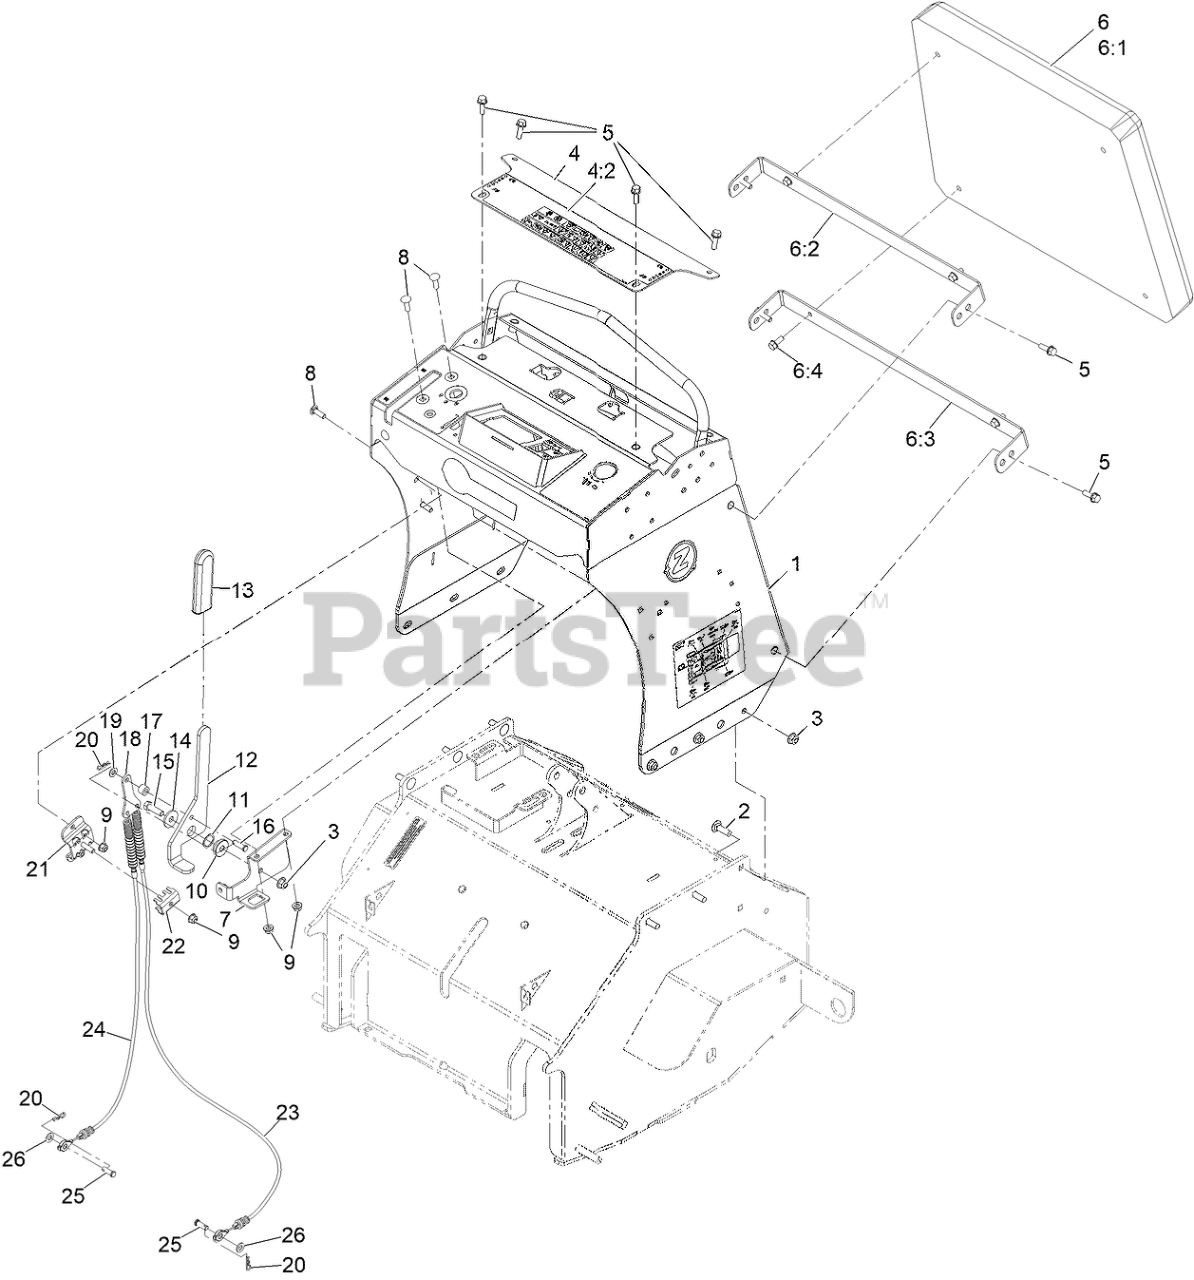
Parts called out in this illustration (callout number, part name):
1	CONTROL TOWER ASM
2	BOLT-CARR
3	NUT-HF, NI
4	CONTROL PANEL ASM
4:2	DECAL-WARNING
5	SCREW-HHF
6	Cushion ASM
6:1	CUSHION-GREY
6:2	BRACKET-PAD, UPPER
6:3	BRACKET-PAD, LOWER
6:4	SCREW-HHF
7	BRACKET-PIVOT, BRAKE
8	SCREW-CARR
9	NUT-HF, NI
10	PIVOT-FLANGE
11	WASHER-WAVE
12	HANDLE-BRAKE
13	GRIP-LEVER
14	WASHER
15	SCREW-HH
16	Pin-Yoke
17	Bushing
18	Yoke-Cable
19	SPACER-NYLON
21	Mount-Cable, Brake
22	Clamp-Cable
23	CABLE-BRAKE, LH
24	CABLE-BRAKE, RH
25	PIN-CLEVIS
26	WASHER-PLAIN
